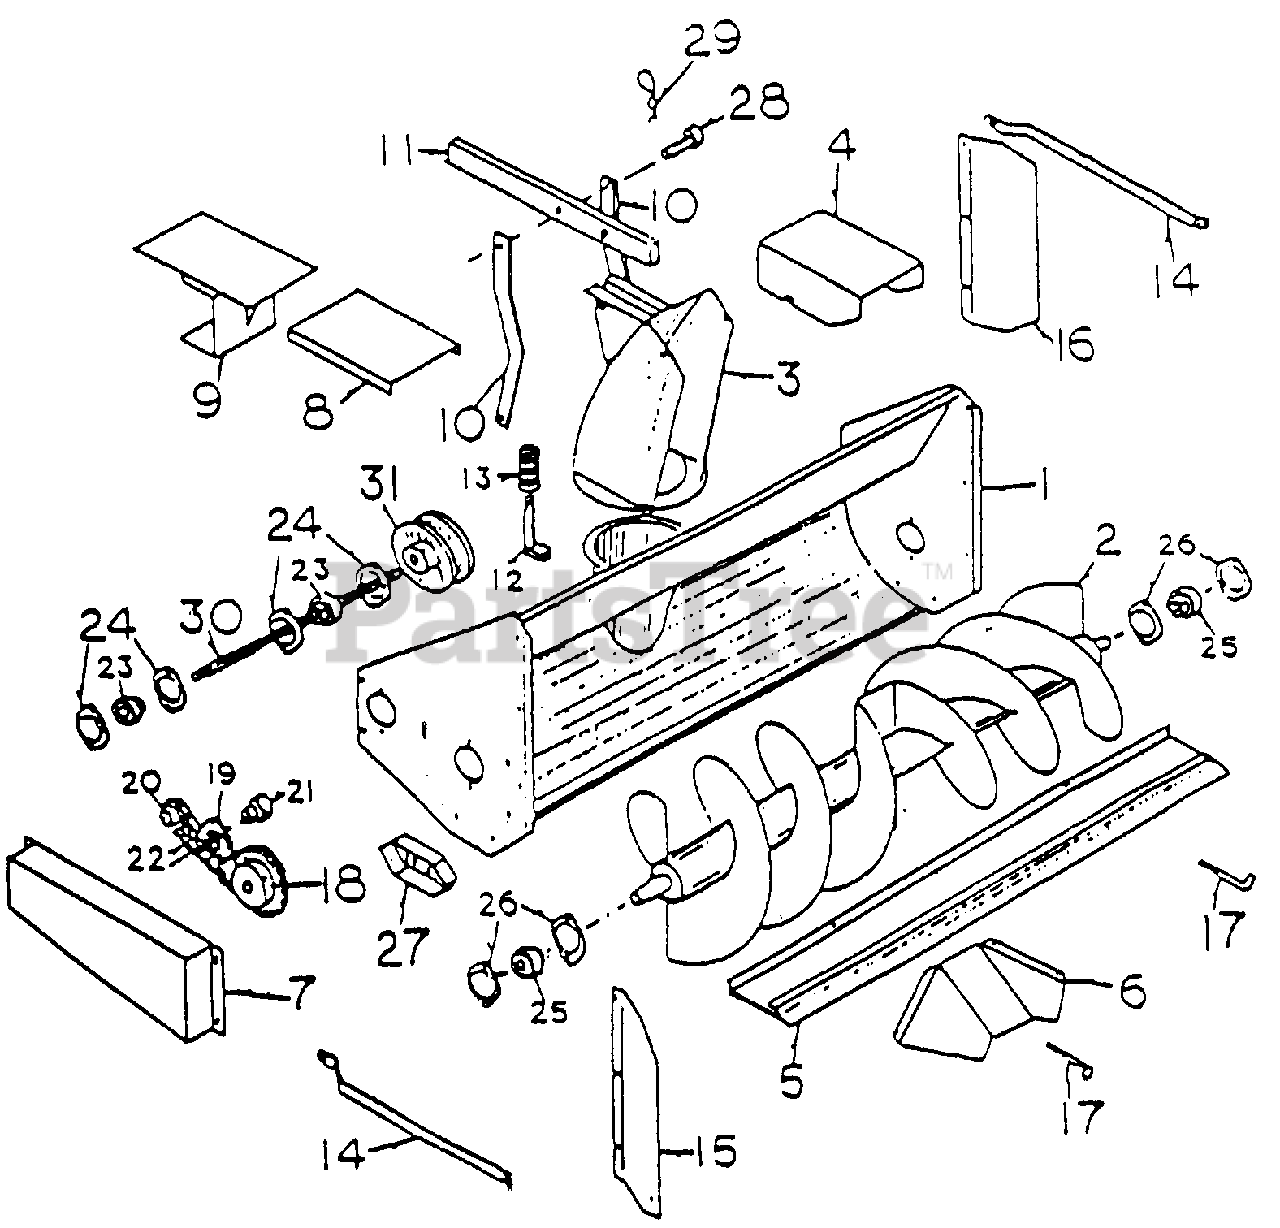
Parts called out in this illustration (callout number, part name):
1	Snow Blower Housing
2	Auger
3	Chute
4	Snow Deflector
7	Chain Guard
8	Belt Guard
9	Belt Retainer
10	Chute Lock Linkage
11	Handle
12	Chute Lock
13	Chute Lock Spring
14	Extender Braces
15	R.H. Extender
17	Blade Bolt
18	Auger Sprocket
19	Idler Sprocket
20	Drive Sprocket
21	Idler Sprocket Bushing
24	3/4 Bearing Flange
25	1 in. Bearing
26	1 in. Bearing Flange
30	Shaft
